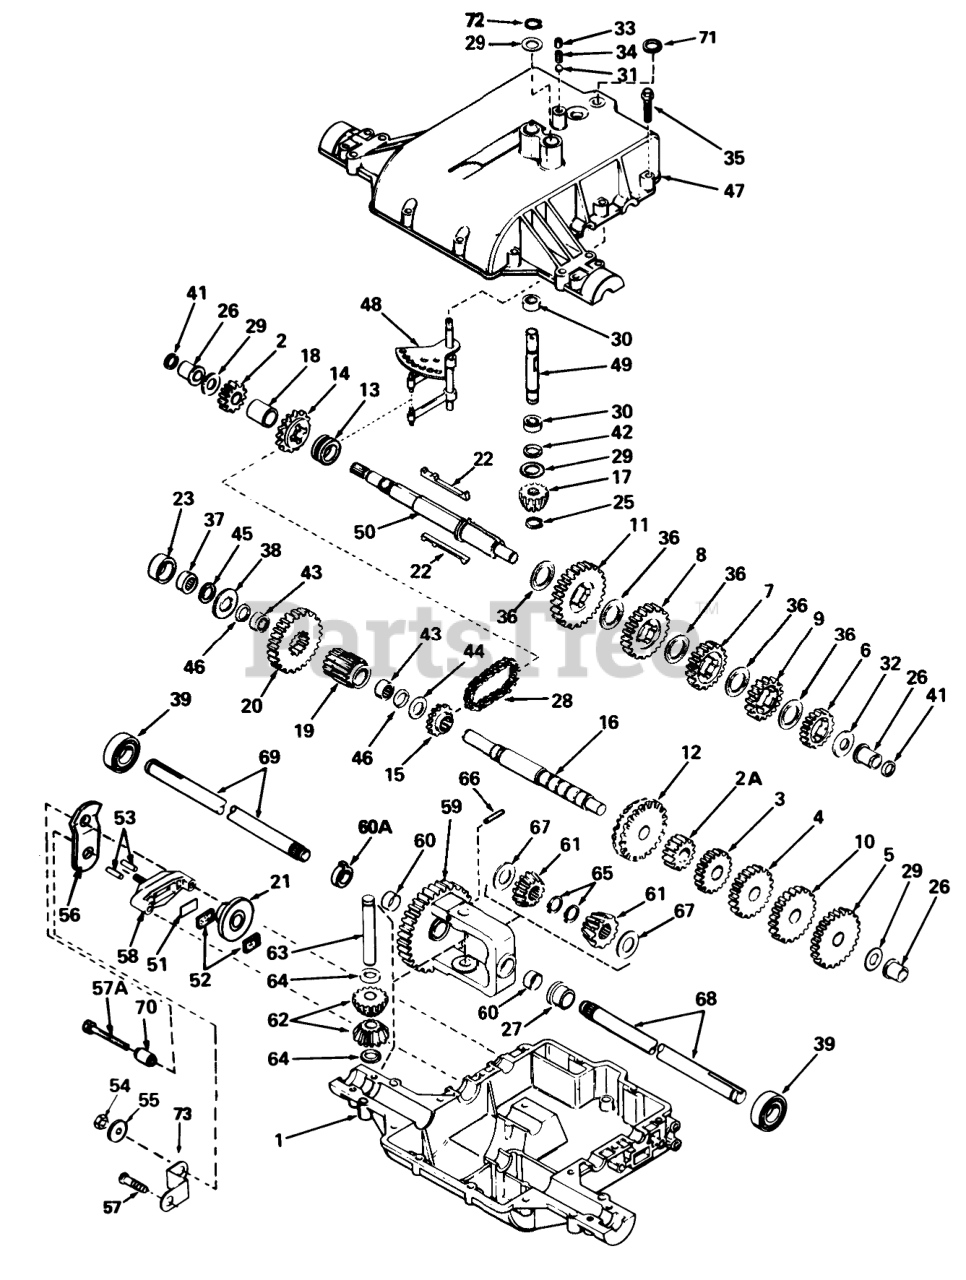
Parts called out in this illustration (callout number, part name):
1	Case-transaxle
2	Gear-Spur 15 Teeth
2A	Gear-Spur, 12 Teeth
3	Gear-Spur, 20 Teeth
4	Gear-Spur, 25 Teeth
5	Gear-Spur (30 teeth)
6	Gear-Spur 20 teeth
7	Gear-Spur, 25 Teeth
8	Gear-Spur, 30 Teeth
9	Gear-Spur (22 teeth)
10	Gear-Spur (28 teeth)
11	Gear-Spur, 37 Teeth
12	Gear-Bevel (42Teeth)
13	Collar-Shift
14	Sprocket-18 Teeth
15	Sprocket-9 Teeth
16	Shaft-Counter
17	Bevel Pinion-Input
18	Spacer
19	Pinion-Output
20	Gear-Output
23	Spacer
25	Ring-Retainer
26	Bushing-Flange
27	Bushing-Flanged
28	Chain-Roller #41
29	Washer
30	Bearing-Needle
31	Ball-Steel
32	Washer
33	Screw-Set
34	Spring
35	Ring Set (.020 O S)
36	Washer
37	Bearing-Needle
38	Washer-Flat
39	Bearing-Ball
41	Ring-Square Cut
42	O Ring
43	Bearing-Needle
44	Washer-Flat
45	Ring-Square Cut
46	Ring-Square Cut
47	Cover-Transaxle
48	Rod & Fork Assembly
49	Shaft-Input
50	Shaft-Brake
51	Brake Pad Plate
52	Brake Pad
53	Dowel Pin
54	Locknut
55	Washer
56	Lever-Brake
57	Ring Set (.020 O S)
57A	Screw-Hex. Flange
58	Holder-Brake Pad
59	Gear Assy.-Differential (Incl. 2 of Ref. #60)
60	Bushing
60A	Bushing
61	Gear Bevel
62	Gear Pinion
63	Drive Pin
64	Thrust Washer
65	Ring-Snap
66	Pin-Roll
67	Washer
68	Axle (14 7/8" Long)
69	Axle (13" Long)
70	Spacer
71	Cut Seal-Square
72	Ring-Snap
73	Bracket-Brake Lever
